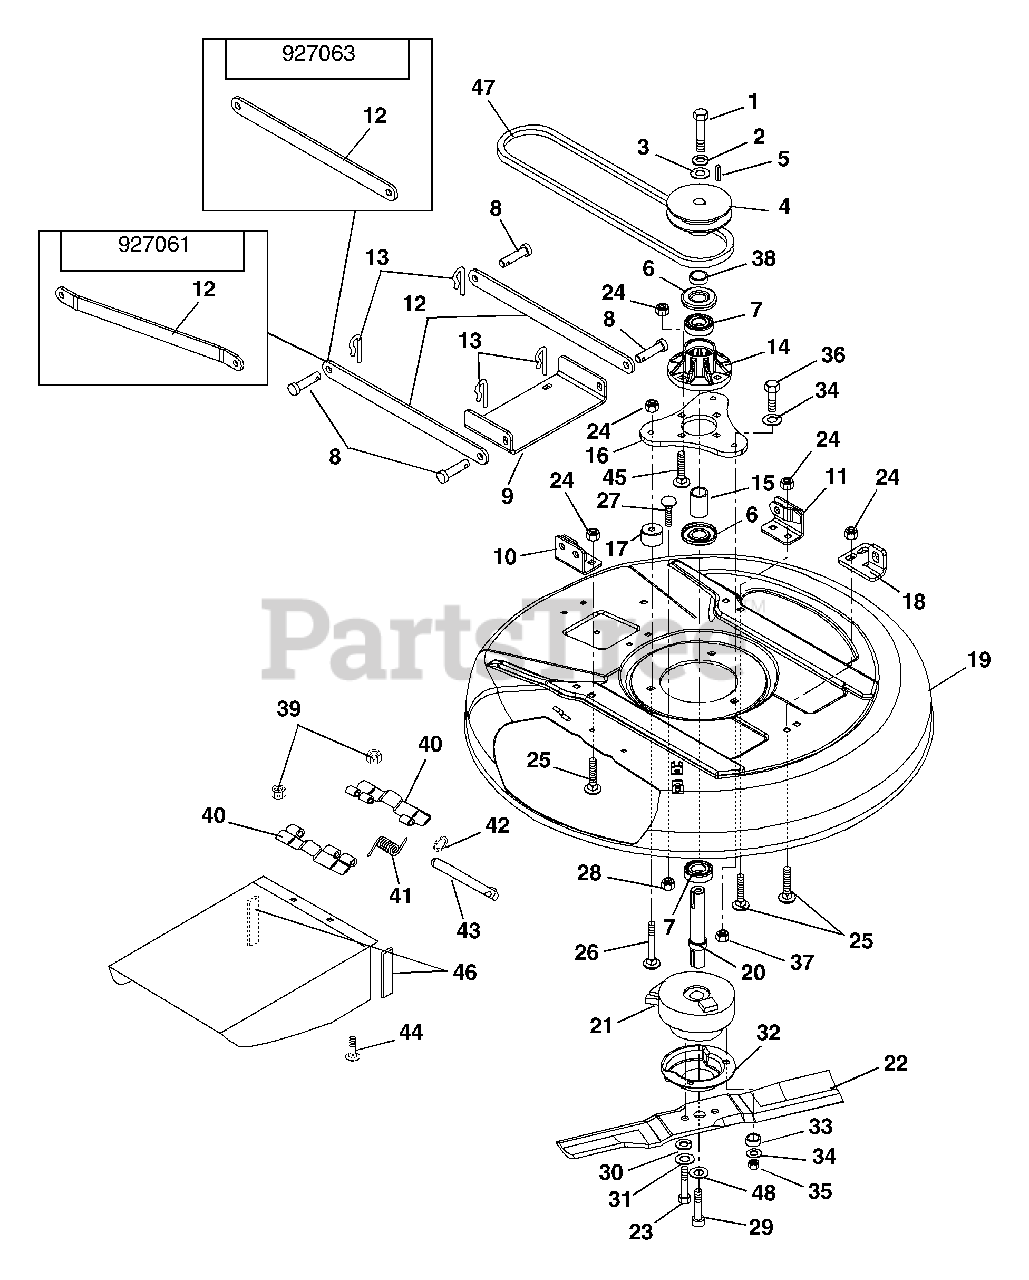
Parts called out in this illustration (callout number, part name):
1	BLT-HEX .38-16X1.00 YZ GR8
2	WSHR-LK .375X.115 HVY YWZC
3	WSHR-FL-STL .406X1.375X.135 YZ
4	PULLEY, 28" DECK INPUT
4	PULLEY, 32" DECK INPUT
5	KEY, SQ .25 X .38 X .25
6	BEARING SLINGER
7	BRG-BALL 1.0X2.0X.56 (1641)
8	PIN-CLEV .494X1.00 BLKZC
9	BRKT, 28" DECK REAR HANGER
9	BRKT, REAR LIFT HANGER (32")
10	BKT-DECK LINK RH
10	WLDMT-DECK LINK (RH)
11	WLDMT-DECK LINK (RH)
11	WLDMT-DECK LINK (LH)
12	STABILIZER LINK 28"
12	LINK STABILIZER 32"
13	CLIP, SPRING
14	ASSY-SPINDLE HSG
15	SPACER, 1.001 X 1.25 X 1.76
16	SPINDLE MOUNT PLATE
17	SPACER-MOUNTING PLATE
18	BRKT, 28" DECK FRONT HANGER
18	BRKT, FRONT LIFT HANGER (32")
19	WLDMT-DECK 32" RAW
20	SHAFT, 28" AND 32" INPUT
21	KIT, CLUTCH (1028 RER)
21	KIT, CLUTCH (1232 RER)
22	BLADE-CUTTING 28"
22	BLADE, 32" RER/ZS
23	BLT-HEX M10X1.25X30 CLS 10.9
24	NUT-LK-TOP-FLG .38-16 BLKZC
25	BLT-RDHDSQNK .38-16X.75 G5BZ
26	BLT-RDHDSQNK .38-16X2.25 G5BZ
27	@BLT-RDHDSQNK .31-18X1.50 G5YZ
28	@NUT-SPNLK-FLG .312-18 YWZC
29	SCR-SKN .5-20X1.25 BTNHD
30	WSHR-LK M 10MM YZ
31	WSHR-FL-STL .406X1.00X.188 YWZ
32	SHIELD, DEBRIS
33	BSHG, SPCR .752X.877X.50 BRZ
34	@WSHR-FL-STL.38X.875X.083 YWZC
35	@NUT-LK-NYL .38-16 YWZC
36	BLT-HEX .38-16X3.00 GR5 FTH YZ
37	@NUT-SPNLK-FLG .375-16 YWZC
38	SPACER 1.008X1.377X.509 ST
39	NUT-LK-FLG .250-20 PL BLK
40	HINGE PLATE
41	SG-TORS .090X.37X.63
42	RG-RTNG-EXT .312X.025
44	@BLT-RDHDSQNK .25-20X.75 G5YZ
45	@BLT-RDHDSQNK .38-16X1.25 G5YZ
46	TRIM BULK
47	KIT, 28" CUTTING IMPROVEMENT
47	KIT, 32" CUTTING IMPROVEMENT
48	WASHER, FLT STL .5X1.75X.187
49	CHUTE-28" DECK
49	CHUTE-32" DECK
